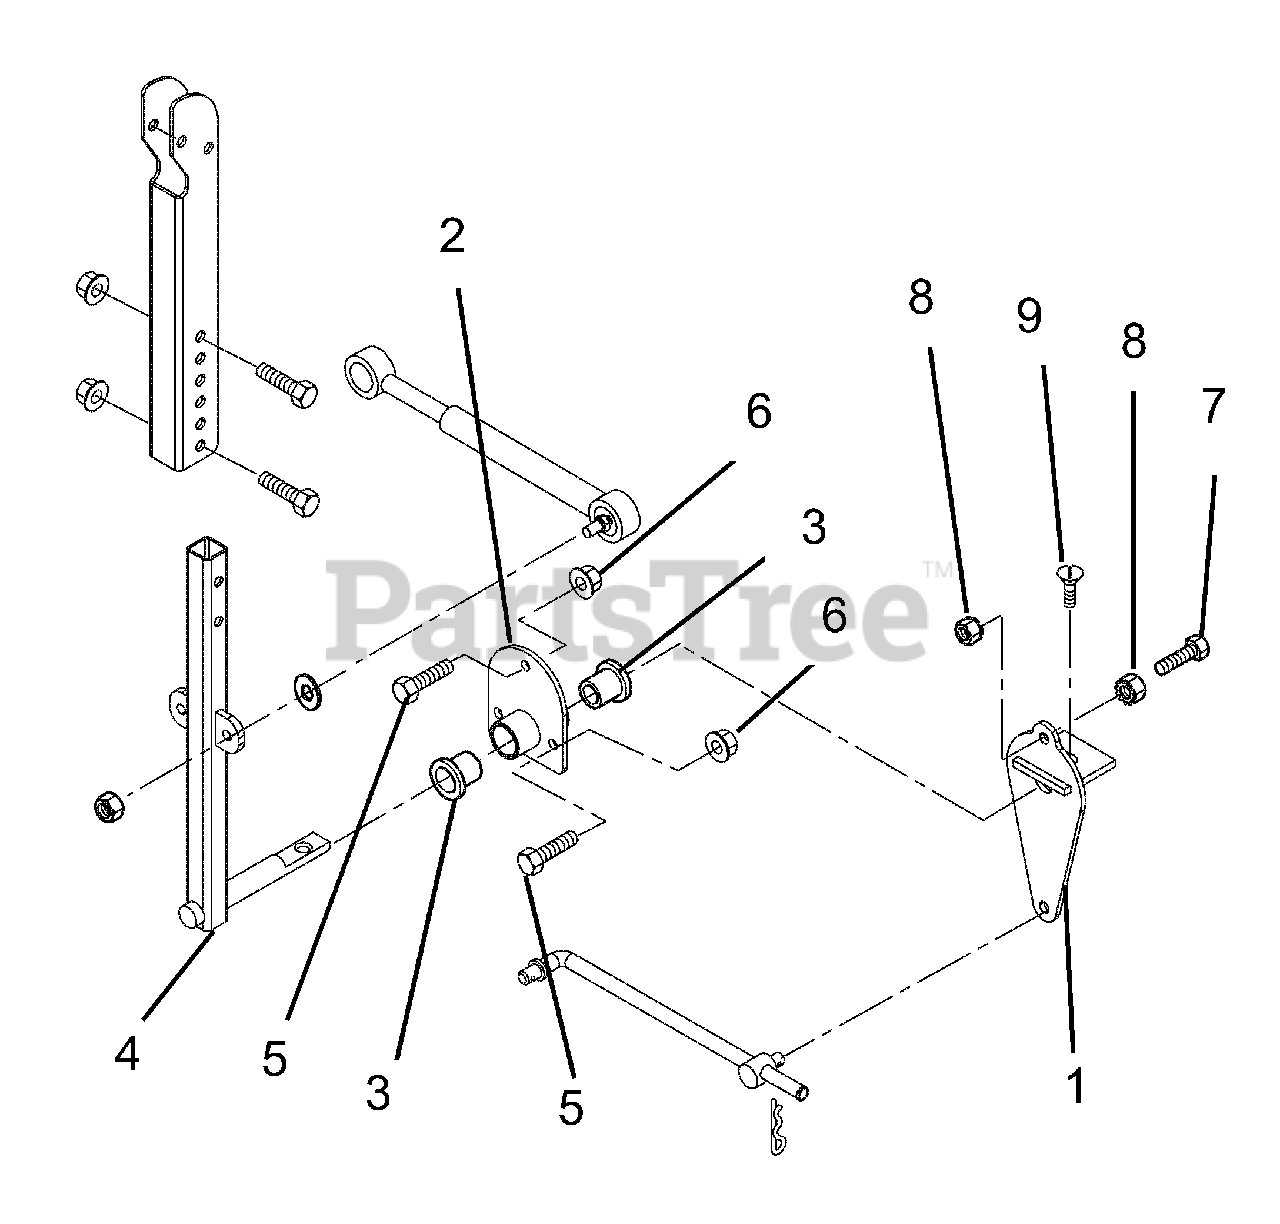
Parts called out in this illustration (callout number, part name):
1	Control Link
2	Steering Bushing Weldment
4	Steering Control Arm
5	5/16" x 3/4" Hex Bolt
6	5/16" Flange Nyloc Nut
7	3/8" x 3" Hex Bolt
8	3/8" Spinlock Flange Nut
9	3/8" x 1" Bolt
